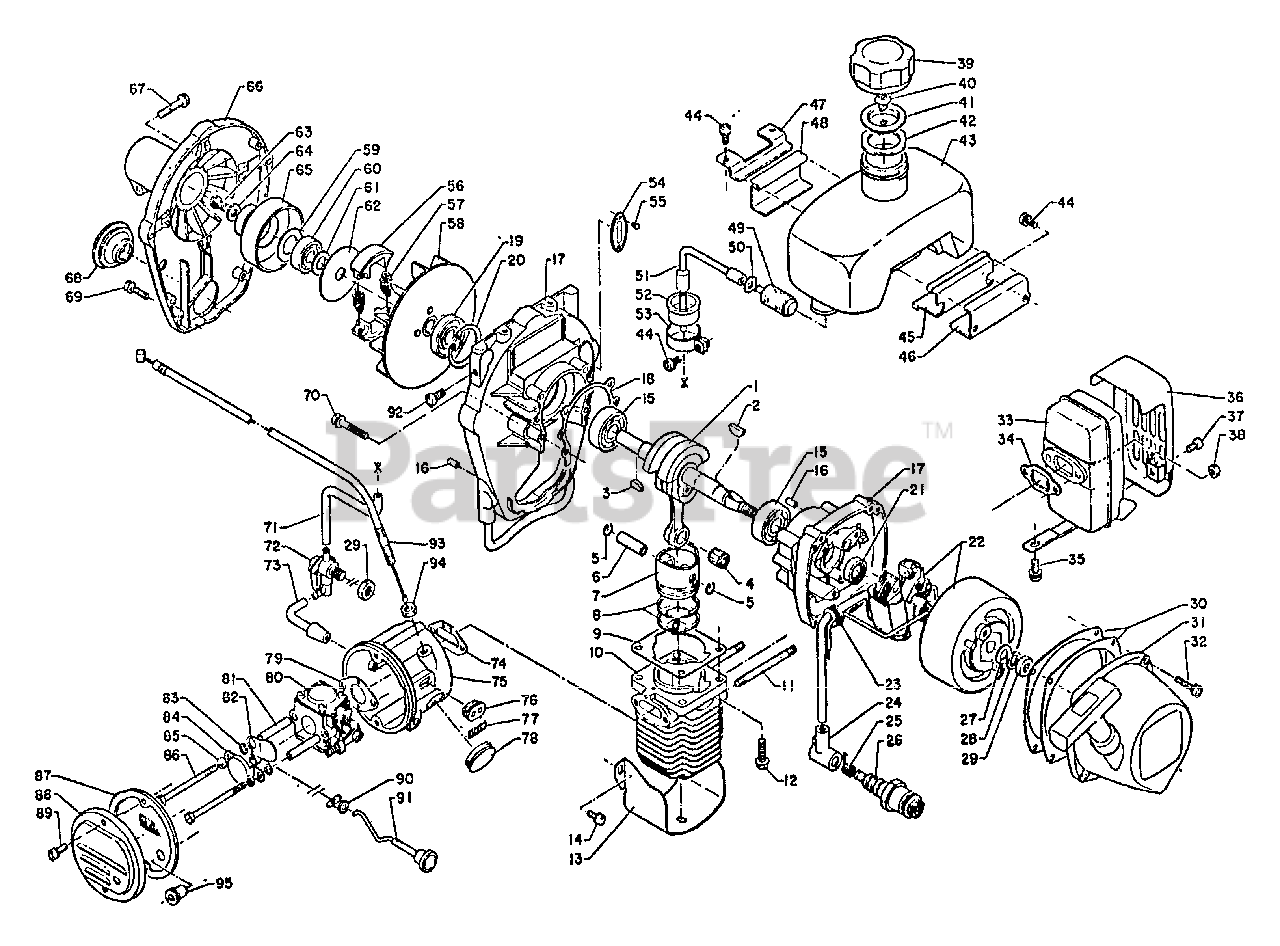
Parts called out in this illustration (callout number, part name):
1	CRANKSHAFT ASSY
4	BEARING, NEEDLE
5	RING, RETAINING
6	PIN, PISTON
7	PISTON
8	RING, PISTON
9	GASKET, CYLINDER
10	CYLINDER
11	STUD
12	SCREW - 5X16
12	WASHER - 5
13	SHIELD, CYLINDER
14	SCREW - 4X8
14	WASHER - 4
15	BEARING, BALL - 6201
16	PIN - LOCATING
17	CRANKCASE KIT
18	GASKET, CRANKCASE
19	SEAL, OIL
20	RING, RETAINING - 32
21	SEAL, OIL
24	CAP, SPARK PLUG
25	TERMINAL, SPARK PLUG CAP
26	SPARK PLUG -- BM-6A
28	LOCKWASHER - 8
30	GASKET, STARTER
31	STARTER ASSY
32	WASHER - 4
32	SCREW - 4X20
33	MUFFLER
34	GASKET, EXHAUST
35	WASHER - 5
35	LOCKWASHER - 5
35	SCREW - 5X10
36	COVER, MUFFLER
37	SCREW - 4X8
38	LOCKNUT - 5
39	CAP
41	HOLDER, VENT
42	GASKET, CAP
43	TANK, FUEL
44	SCREW - 4X8
44	LOCKWASHER - 4
45	CUSHION, FUEL TANK
46	BRACKET, FUEL TANK
47	BRACKET, FUEL TANK
48	CUSHION, FUEL TANK
49	FILTER, FUEL
50	WASHER - 6
51	PIPE - FUEL
52	CONNECTOR
53	CLAMP
54	PLATE, MODEL
55	RIVET
56	SHOE, CLUTCH
57	SPRING, CLUTCH
58	FAN
59	WASHER, CLUTCH
60	BEARING, BALL - 6000
61	WASHER, CLUTCH
62	PLATE, CLUTCH
63	SCREW - 6X10
64	WASHER - 6
65	DRUM, CLUTCH
66	CASE, FAN
67	BOLT - 5X25
68	SEAL, DUST
69	SCREW - 4X18
69	WASHER - 4
70	SCREW - 5X28
70	LOCKWASHER - 5
70	WASHER - 5
71	PIPE, FUEL - OUTER
72	FUEL VALVE ASSY
73	PIPE - FUEL
74	GASKET, INTAKE
75	CASE, CARBURETOR
77	LABEL - CAUTION
78	PLUG
79	GASKET, INTAKE
80	CARBURETOR
81	SPACER
82	SHUTTER, CHOKE
83	WASHER
84	PLATE, PREVENT
87	FILTER, AIR
88	COVER, AIR FILTER
89	SCREW - 4X12
90	GROMMET
91	ROD, CHOKE
92	SCREW - 5X10
93	CABLE, THROTTLE
95	GROMMET
